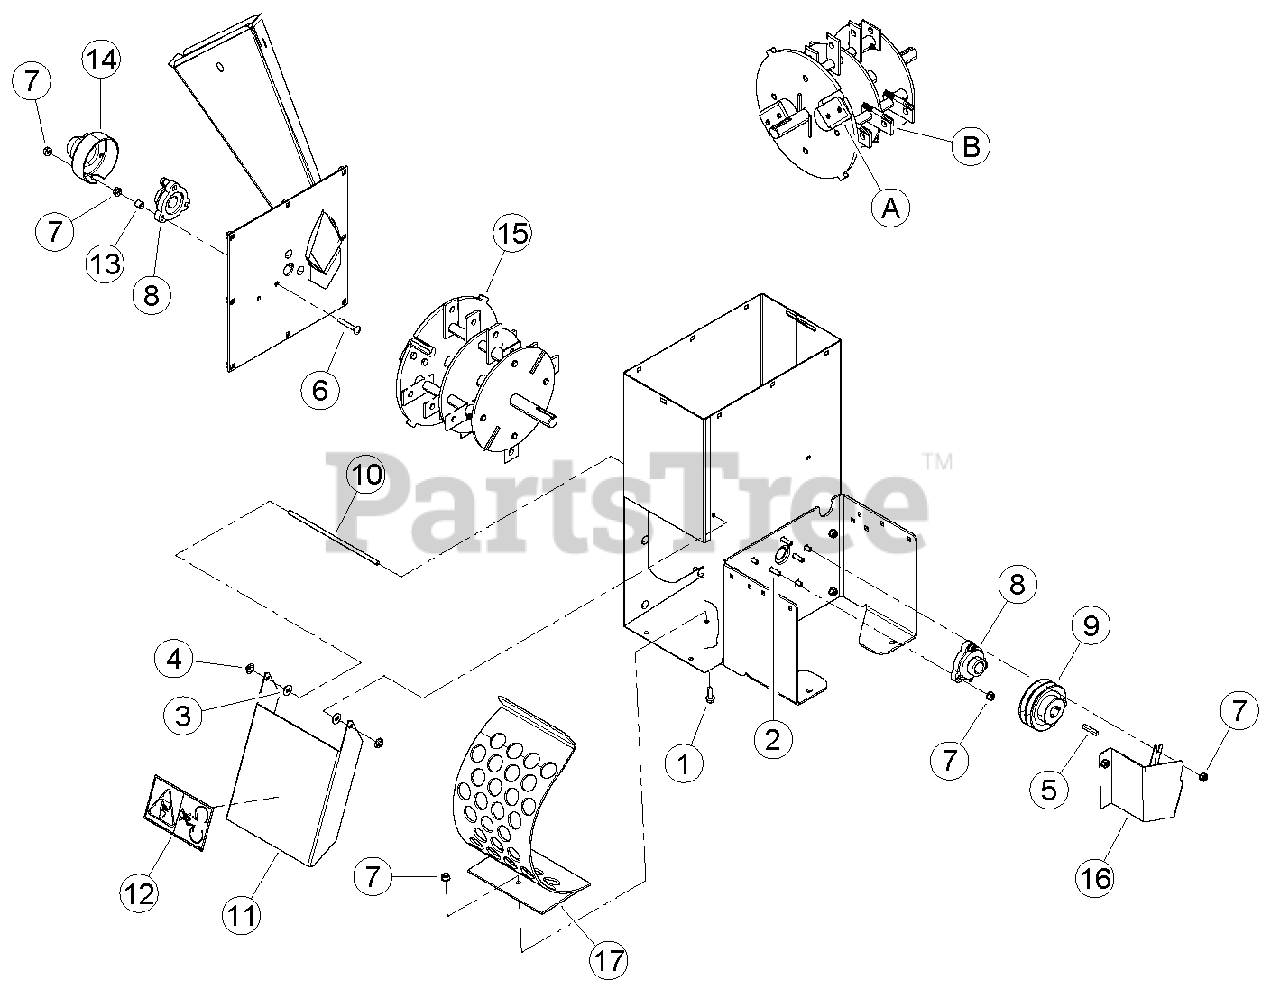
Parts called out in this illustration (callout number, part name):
1	BOLT, 5/16 X 1 FLANGE NC
2	BOLT, 5/16 X 1-1/4 CRG GR5 ZP
3	WASHER, 5/16 ID 7/8 OD NYLON FLAT
4	PUSHNUT, 5/16" ZP
5	KEY, 1/4 SQUARE X 1-1/2 LONG PLAIN
6	BOLT, 5/16 X 2CRG GR5 NC ZP
7	NUT, 5/16-18 NYLOCK-FLANGE
8	BEARING, 1" FLUSHMOUNT CAST W/COLLAR
9	PULLEY, 4 X 1 2A GROOVE
10	SHAFT, DOOR PIVOT
11	DOOR, 8 HP DISCHARGE W/ DECAL
12	DECAL, BLADE DANGER ISO
13	SPACER, .54 OD X .50" LG
14	CAP, ROTOR SHAFT END CAP
15	ASSEMBLY, BALANCED RENTAL ROTOR
16	SHIELD, LOWER
17	WELDMENT, WIDE COARSE TAPERED
A	KIT, TOOL STEEL BLADE
B	KIT, 3" WIDE SHREDDER KNIVES
